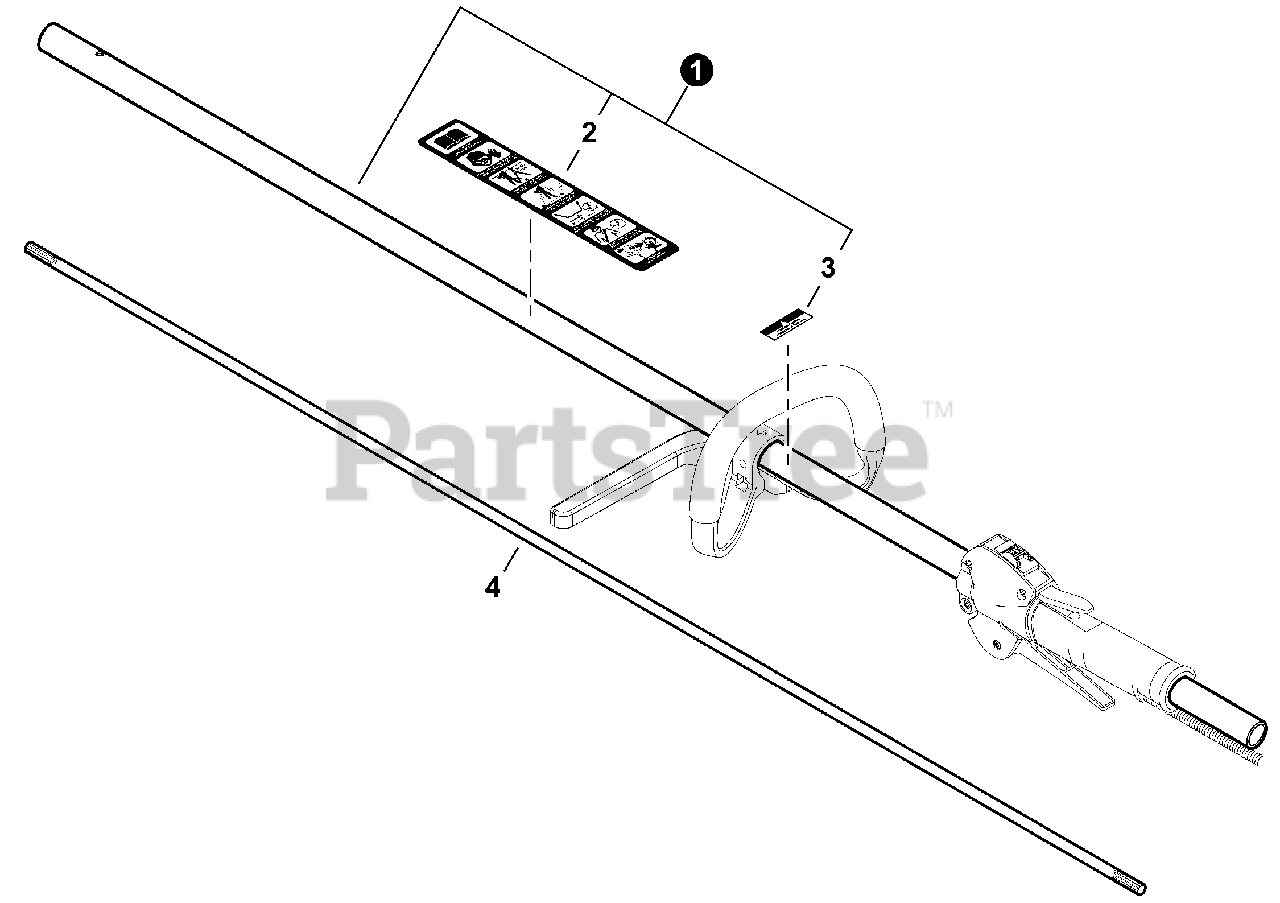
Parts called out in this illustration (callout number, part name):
1	MAIN PIPE ASSY
2	LABEL, CAUTION (BLADE CAPABLE)
3	LABEL, HANDLE
4	DRIVESHAFT
